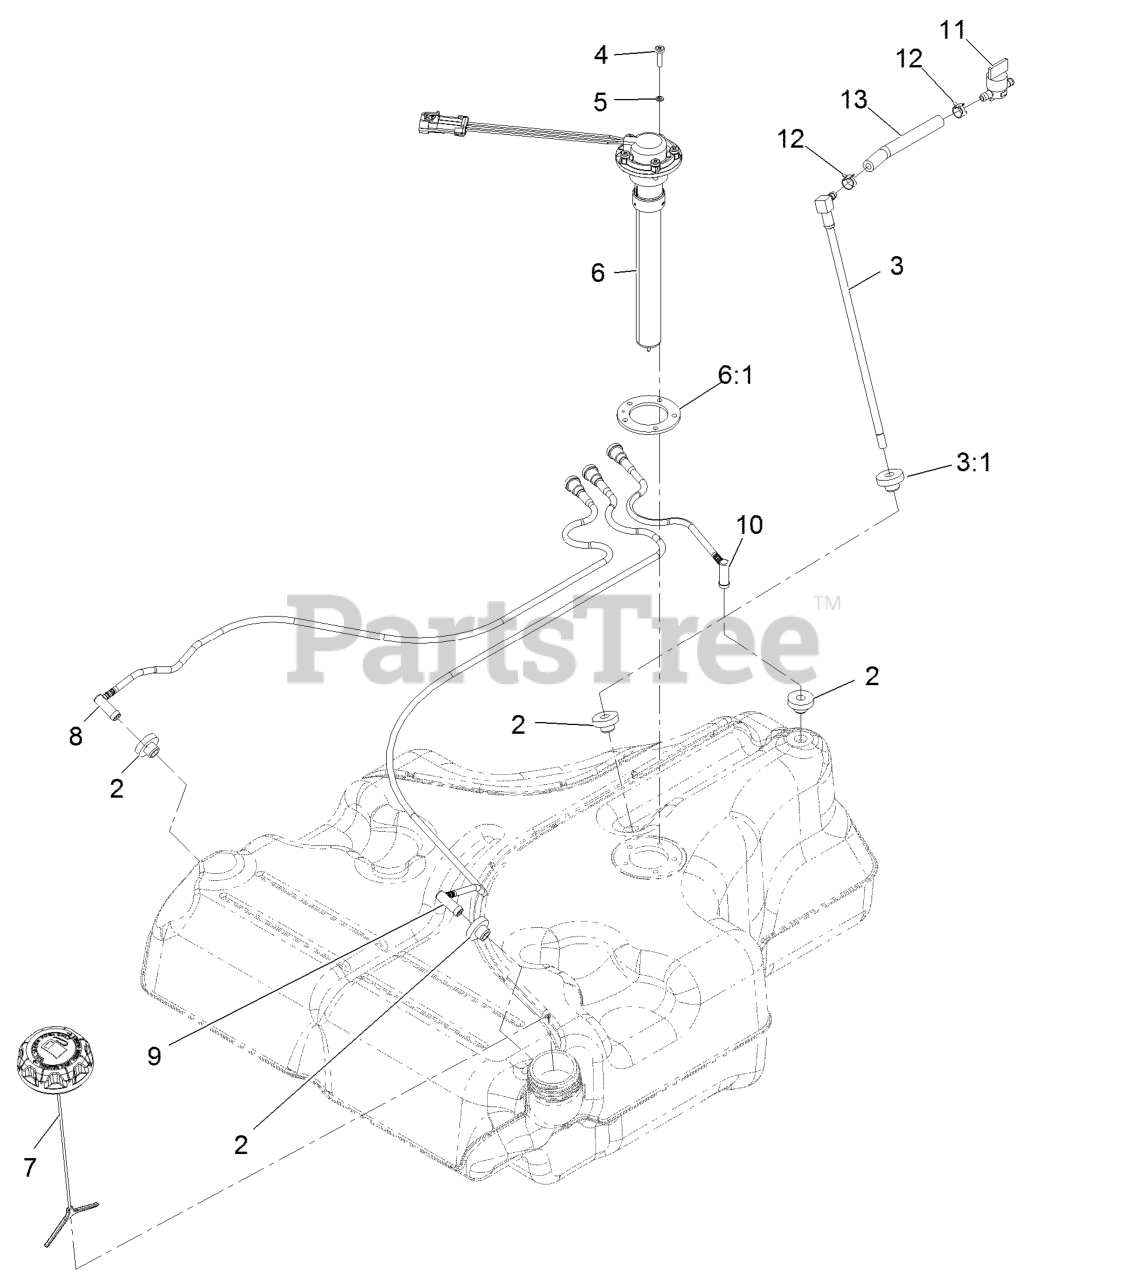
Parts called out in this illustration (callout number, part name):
2	BUSHING
3	FUEL LINE KIT (WITH GROMMET)
3:1	BUSHING
4	SCREW-PAN
5	WASHER-LOCK
6:1	GASKET-SENDER, FUEL
7	CAP-FUEL, RATCHETING
8	RH VENT LINE KIT (WITH GROMMET)
9	LH VENT LINE KIT (WITH GROMMET)
10	REAR VENT LINE KIT (WITH GROMMET)
11	VALVE-FUEL
12	CLAMP-HOSE
13	HOSE-FUEL
